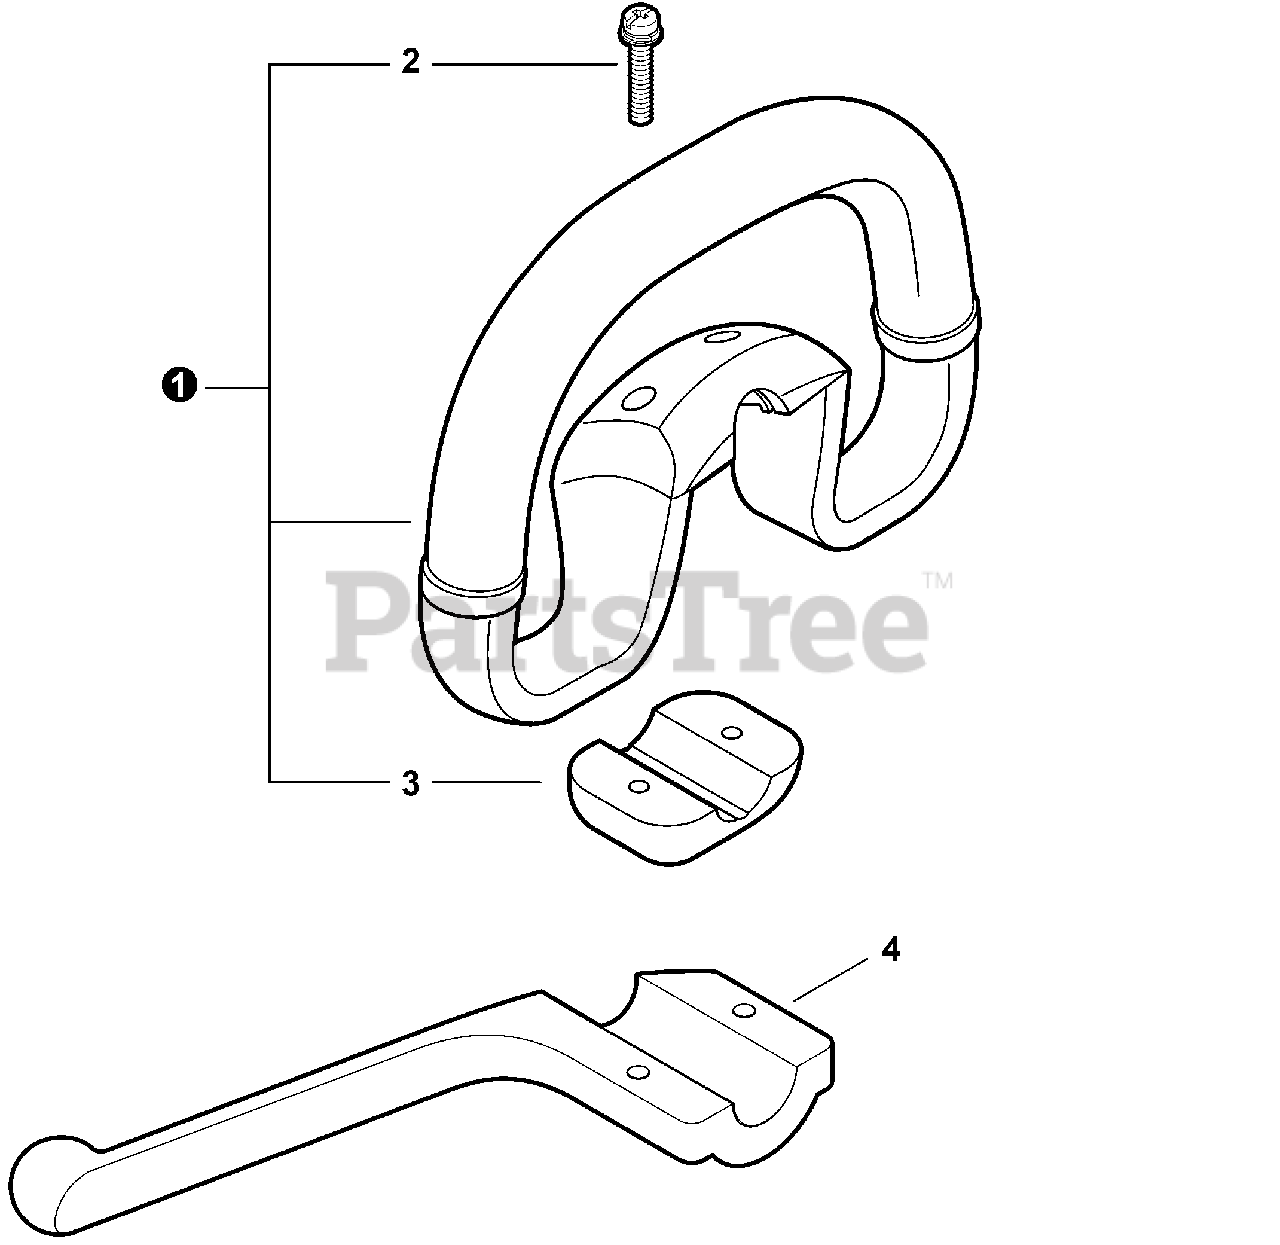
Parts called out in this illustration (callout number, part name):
1	FRONT HANDLE KIT
2	SCREW - 5×40
3	FIXTURE, HANDLE
4	BAR, BARRIER
